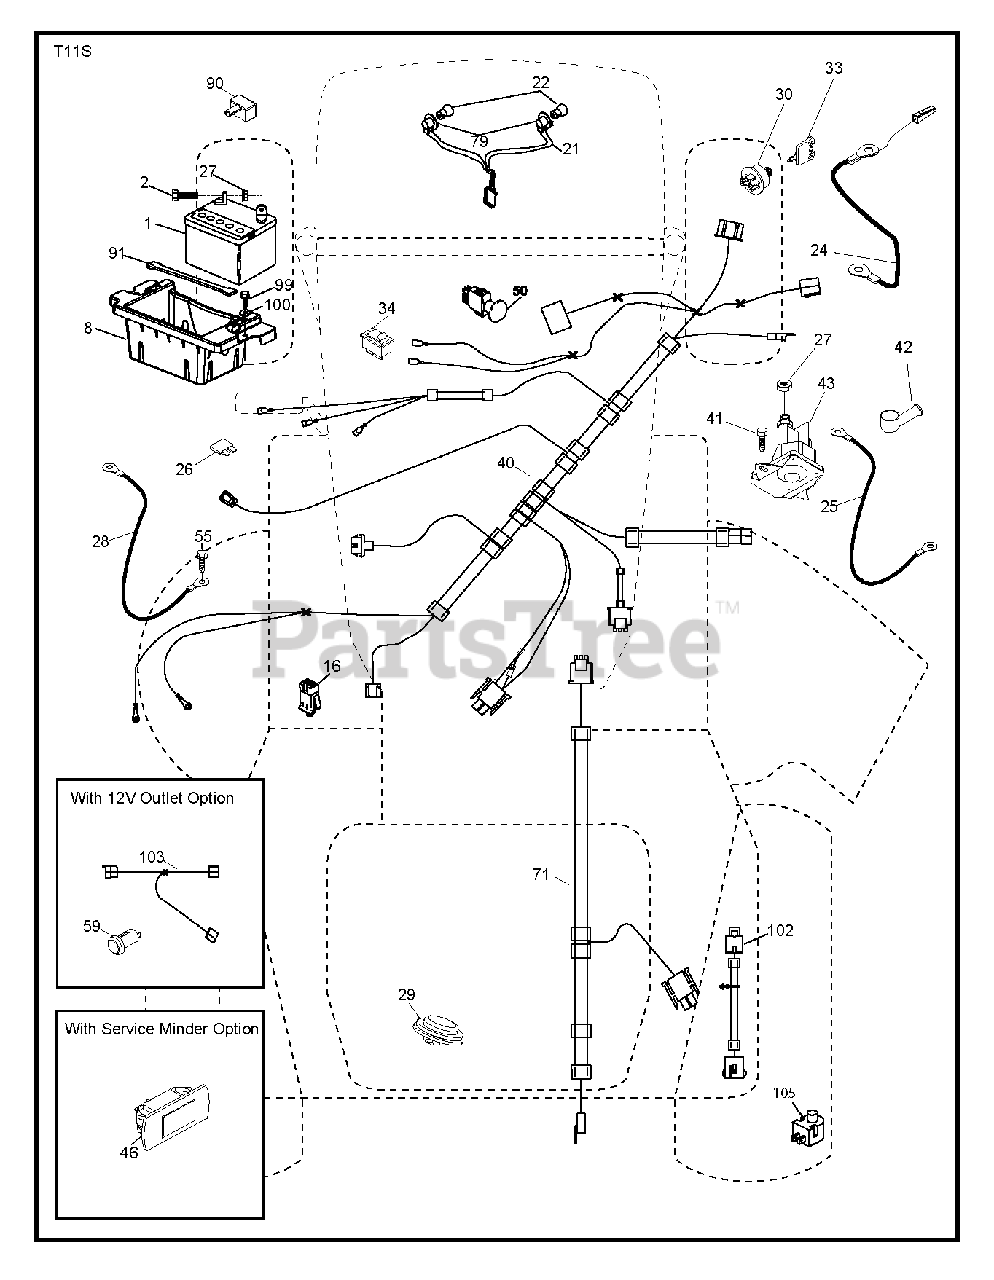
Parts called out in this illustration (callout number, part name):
1	REPL BY 532 12 38-99
8	BOX.BATTERY.MOUNT.FRONT.LT
16	SWITCH INTERLOOK PUSH-IN
21	HARNESS.LIGHT W/4152J BULBS
22	LIGHTBULB
24	CABLE.BATT.POS.WIRE.TG.DA SOL
25	CABLE.STARTER.6G.BL/RED.17.5
26	FUSE 20AMP
27	NUT
28	CABLE GROUND 6 GA 21" 90T BLK
29	SWITCH.SEAT.DELTA.OPC.
30	SWITCH.IGN.DELTA.W.LGH.ROS
33	KEY.CHAIN.BLISTER.PACK.GEN.USA
34	SWITCH LT
40	HARNESS IGN. DASH
41	SCREW
42	TERMINAL COVER
43	SOLENOID.W/BRASS.PLUNG
46	GUAGE.SRVCMNDR.HRMTR.
50	PTO SWITCH
55	SCREW 5/16"
71	HARNESS-CHASSIS SUB
79	BULB HOLDER ASM.
90	COVER.TERMINAL.BATTERY
91	STRAP, BATTERY MOUNT
99	SCREW HEXWSHR 1/4-20X3/4
102	HARNESS PIGTAIL PCH TEX ROS
105	REVERSE SWITCH
